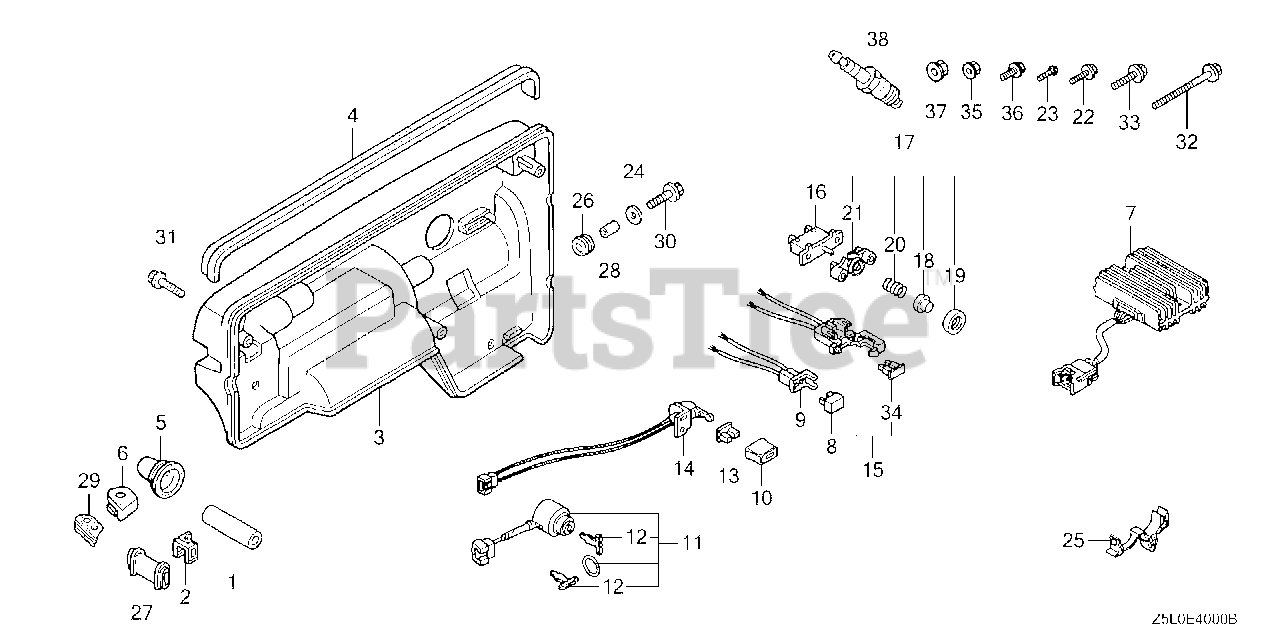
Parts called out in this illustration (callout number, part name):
8	RECTIFIER ASSY., SILICON (SHINDENGEN)
11	SWITCH ASSY., COMBINATION (HONDALOCK)
12	KEY (HONDALOCK)
15	CASE, FUSE
22	BOLT, FLANGE (6X12) (CT200)
34	FUSE, BLADE (10A)
35	NUT, FLANGE (5MM)
36	BOLT, FLANGE (6X10)
